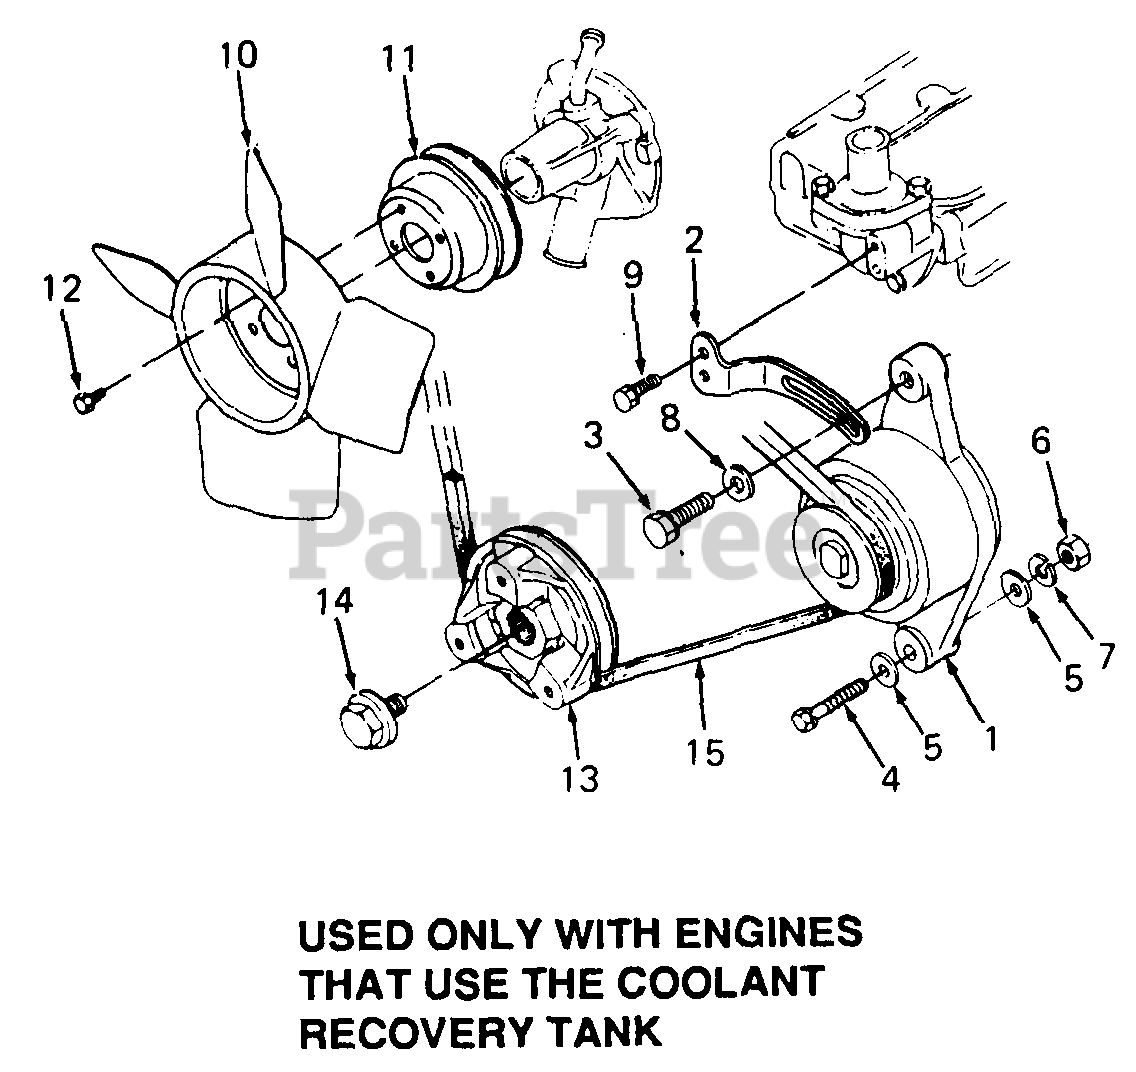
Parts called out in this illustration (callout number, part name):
1	Alternator Assy
2	Stay, Alternator
5	Washer, Plain
7	Washer, Spring
8	Washer, Plain
13	Pulley, Fan Drive
